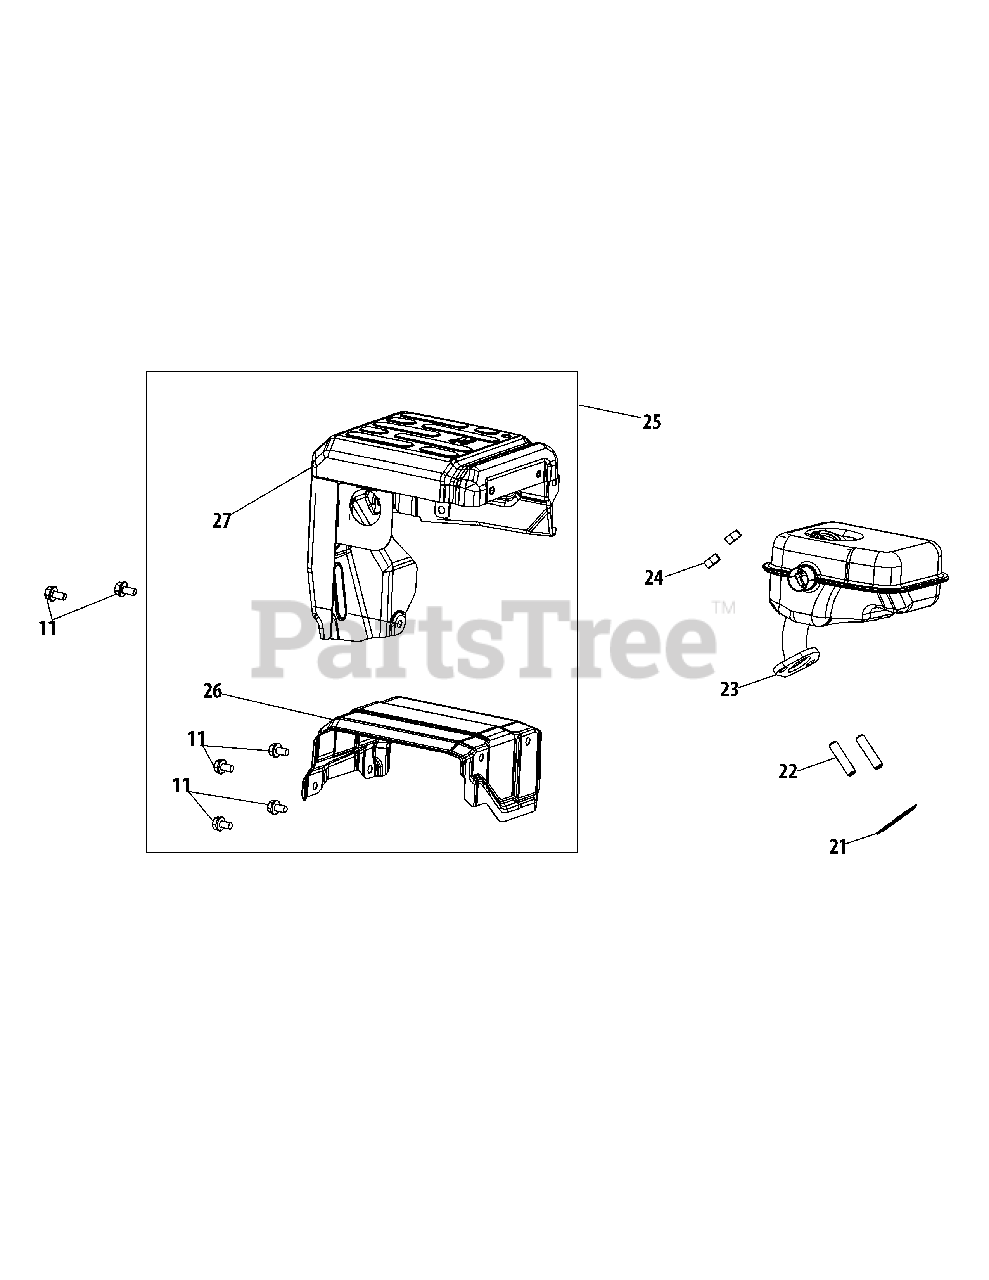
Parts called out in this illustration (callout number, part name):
11	Bolt, M6×12
21	Gasket, Muffler
22	Stud, M8×34
23	Muffler
24	Nut, M8
25	Muffler Guard
26	Muffler Inner Shield
27	Muffler Shield
